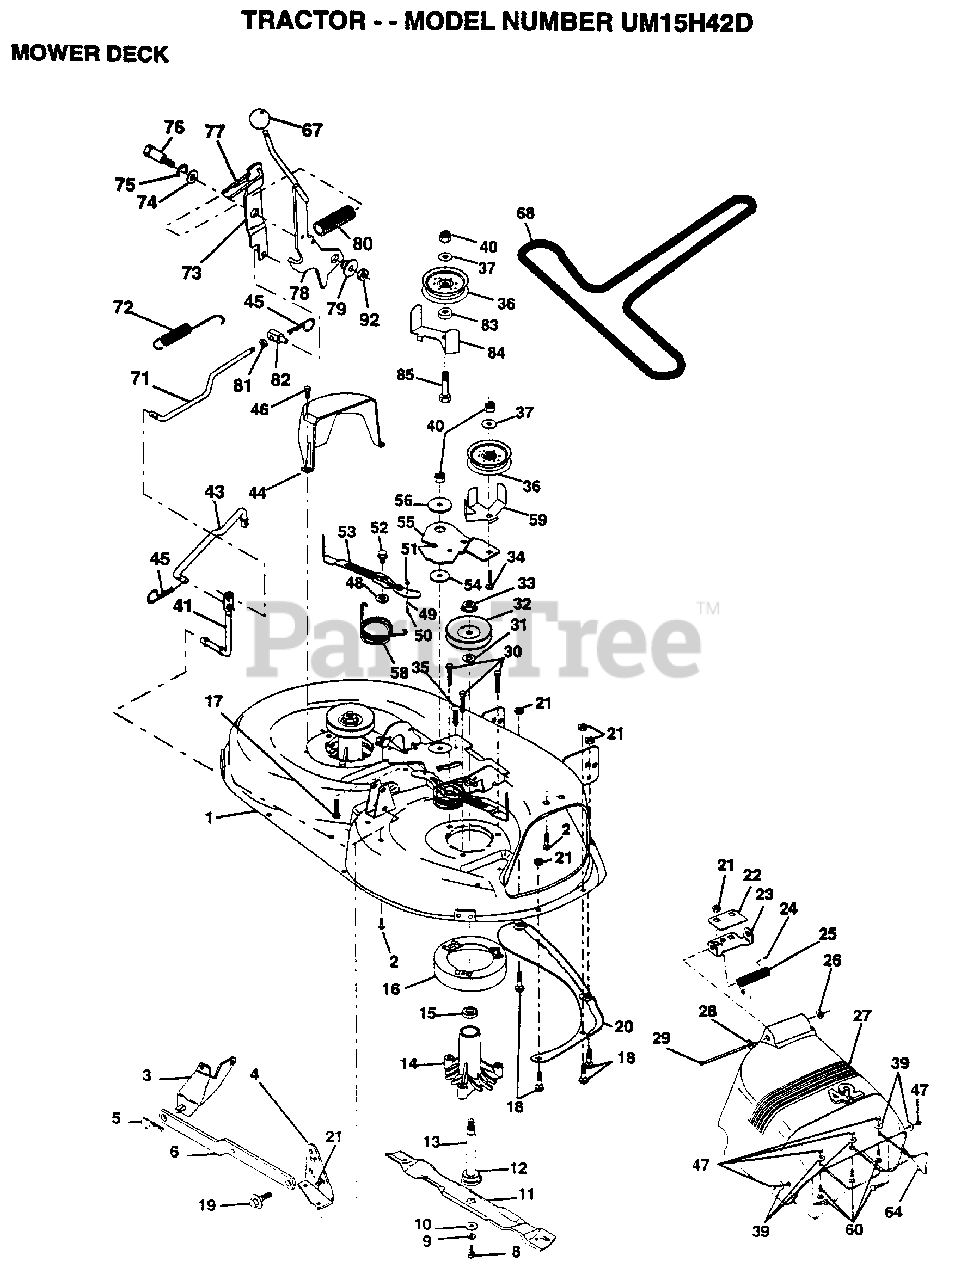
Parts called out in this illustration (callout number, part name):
1	DECK.WELD.42.
2	BOLT
3	BRKT ASM SWAY BAR
4	BRKT DECK SW BAR
8	BLADE BOLT
10	WASHER.HARD.BLADE
11	"BLADE.42"" HIPERF"
12	BEARING.BALL
14	HSG ASM MANDREL
15	BEARING
16	STRIPPER RND MWR
17	BOLT RDHD 3/8-16
18	BOLT
19	BOLT SHD 5/16-18
22	STIFFENER BRKT
23	DEFLECTOR BRKT
24	CAP-SLEEVE LT
25	SPRING TORSION
26	NUT PUSH M
27	DEFLECTOR.CLIP.TU
28	WASHER
29	HINGE ROD
31	WASHER
34	BOLT
35	XMAS TREE FASTNER
36	FLAT IDLER PULLEY
37	WASHER
41	PIVOT ROD
43	ROD CLUTCH W/NIBS
44	GUARD MAND LH BLK
45	RETAINER M
46	SCREW.1/4-20X5/8
48	HARD SMALL WASHER
50	SHOULDER BOLT
51	LOCKNUT
52	BOLT.SHLD.5/16-18
53	BRAKE PAD ARM ASM
54	HARDENED WASHER
56	SPACER RETAINER
58	SPRING TORSN BRAK
59	GUARD IDLER TUV
60	BOLT.CARRIAGE.UNC
64	GUARD.FOOTREST.42
67	KNOB T(3/8 HOLE)
68	BELT.V.T-PATH
71	ROD CLUTCH 38/42
72	RETURN SPRING
73	CLUTCH ARM SECOND
74	WASHER
75	RING
76	SHOULDER BOLT
77	SPRING KEEPER
79	BUSHING
81	NUT
82	TRUNION ADJ
83	WASHER
85	BOLT RDHD 3/8-16
92	NUT
